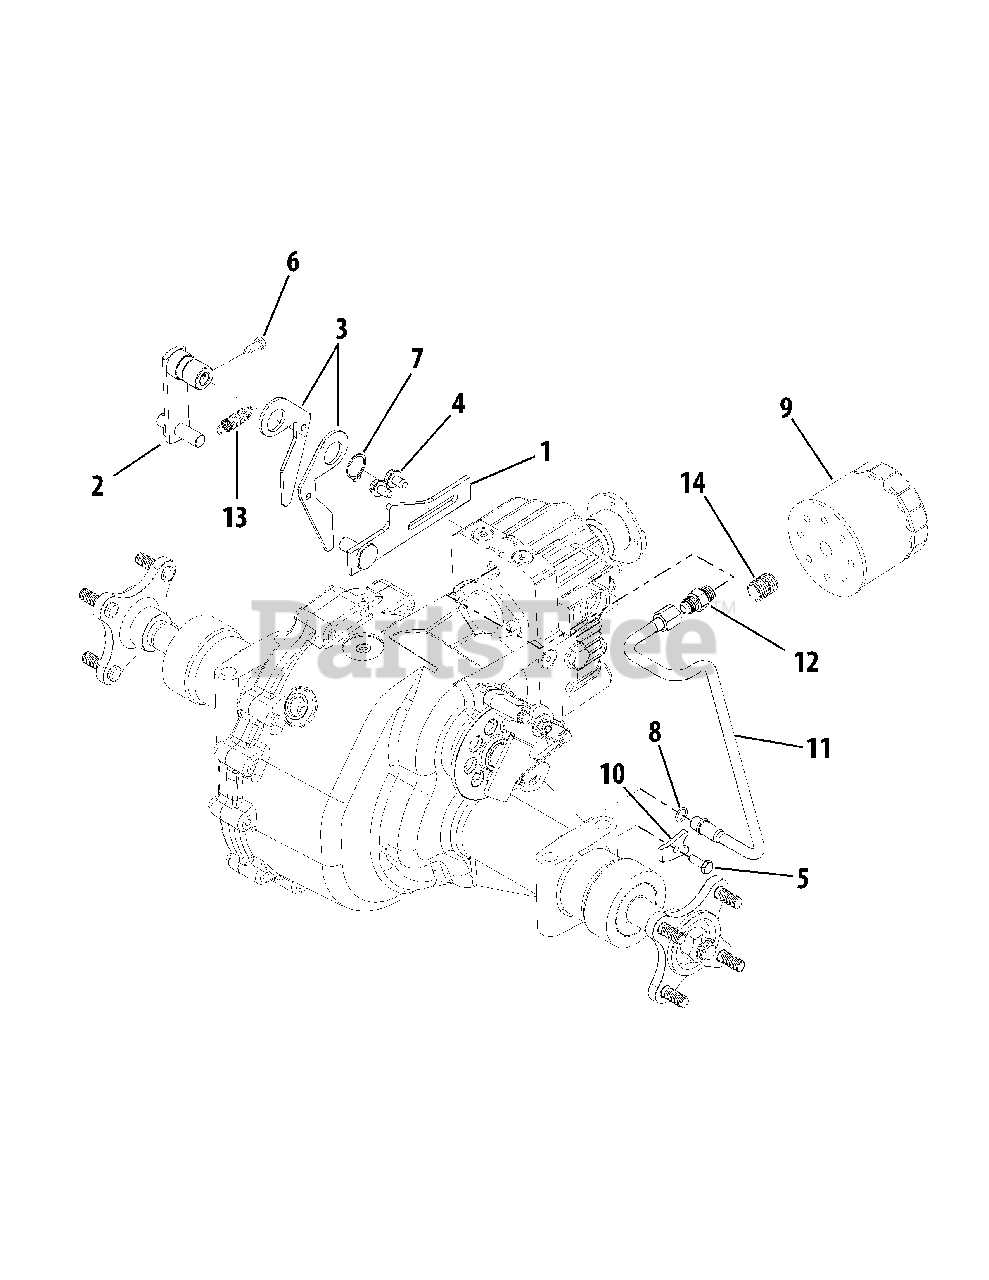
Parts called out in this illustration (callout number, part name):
1	Bracket, Neutral Return
2	Arm Assembly, Control
3	Arm, Neutral
4	Screw, Hex Wash Hd Tapp, 5/16-18 x .50
5	Screw, Hex Cap, 1/4-20 x .75 GR5
6	Screw, Special Hex Cap, 5/16-24 x .625
7	Ring, Snap, .875 Shaft
8	O-Ring, .426 ID x .566 OD x .07
9	Filter, Oil
10	Clamp, Tube, .50
11	Tube, Hydro Pickup
12	Fitting, Hydraulic
13	Spring, Extension
14	Nipple, Oil Filter
